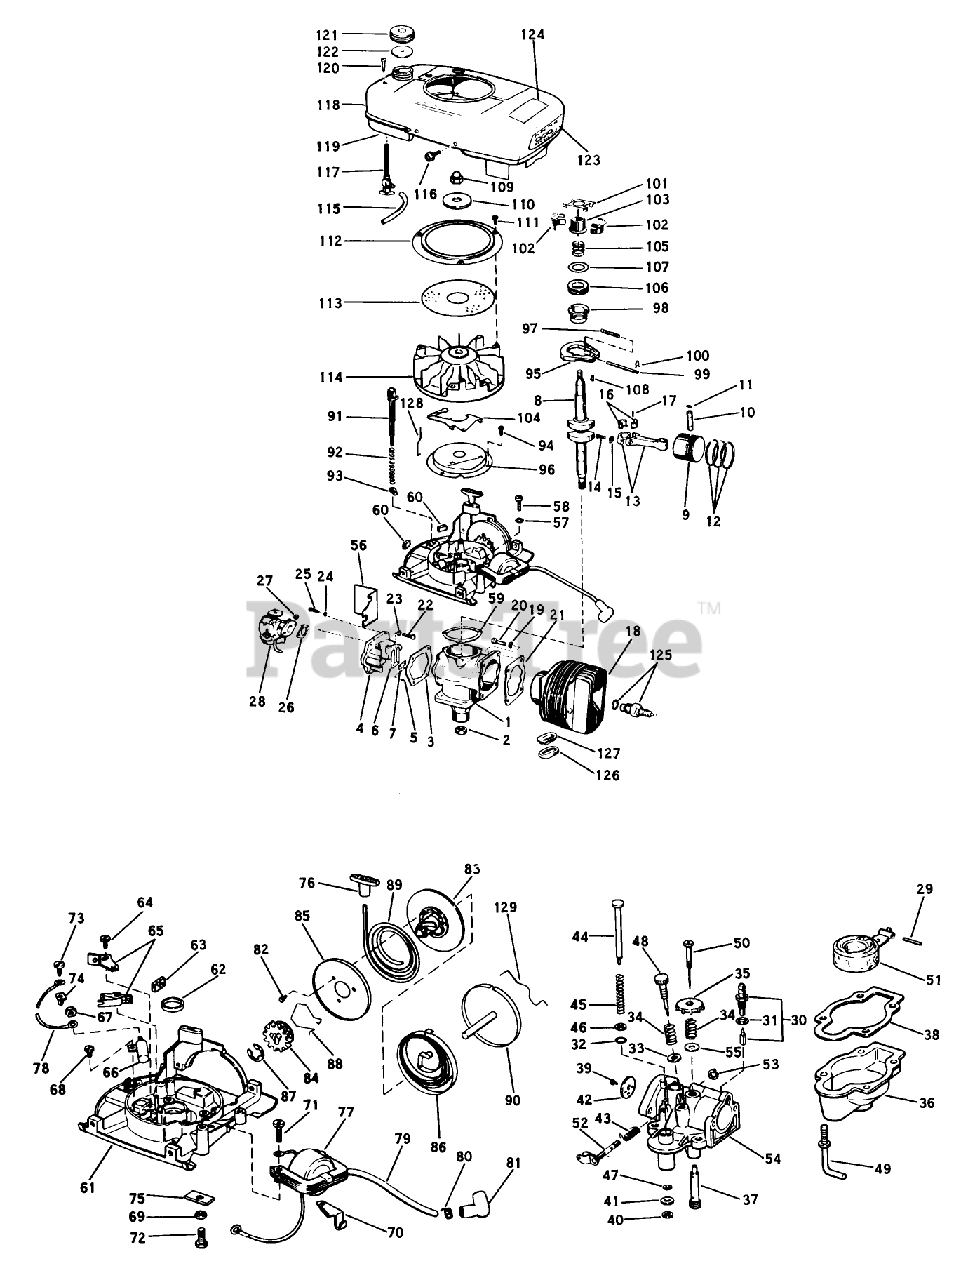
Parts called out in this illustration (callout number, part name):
1	Crankcase Reed Plate Assy.
7	PLATE-BACKUP, REED
8	Crankshaft
11	RING-RETAINING
16	LINER ASM
21	GASKET S
25	SCREW S
26	GASKET S
27	STOP NUT
28	Governor Assembly
34	Spring-Ndl. Adj.
37	NOZZLE S
38	GASKET S
41	Washer-Rubber
42	THROTTLE DISC S
44	DISC. SEE PRC4
48	Screw-Idle Adjustment
50	NEEDLE AY. S
52	THROTTLE LEVER S
53	RING GRIP S
54	Carburetor Body Assy.
59	GASKET S
65	BREAKER AY. S
70	Clip-High Tension Wire
72	SCREW S
73	Screw Shut-off Switch
74	NUT - CLIP
79	LEAD AY. S
81	Cover-Rubber
86	SPRING S
88	STARTER SPRING S
92	SPRING S
94	SCREW S
95	FLYWEIGHT S
96	DUST COVER S
97	SPARK ADV. SPRING S
98	SPARK ADV. S
99	PIN,SPARK ADV. S
100	SPARK ADJ. SPRING
103	COLLAR S
104	LEVER-GOVERNOR S
106	THRUST COLLAR S
112	Ring-Flywhl. Scrn.
116	SCREW S
117	VALVE&SCREEN SM
121	Gas Cap
122	Gasket-Gas Cap
123	Decal-Lawn-Boy
124	Decal-Instruction
125	Spark Plug
129	SPRING S
